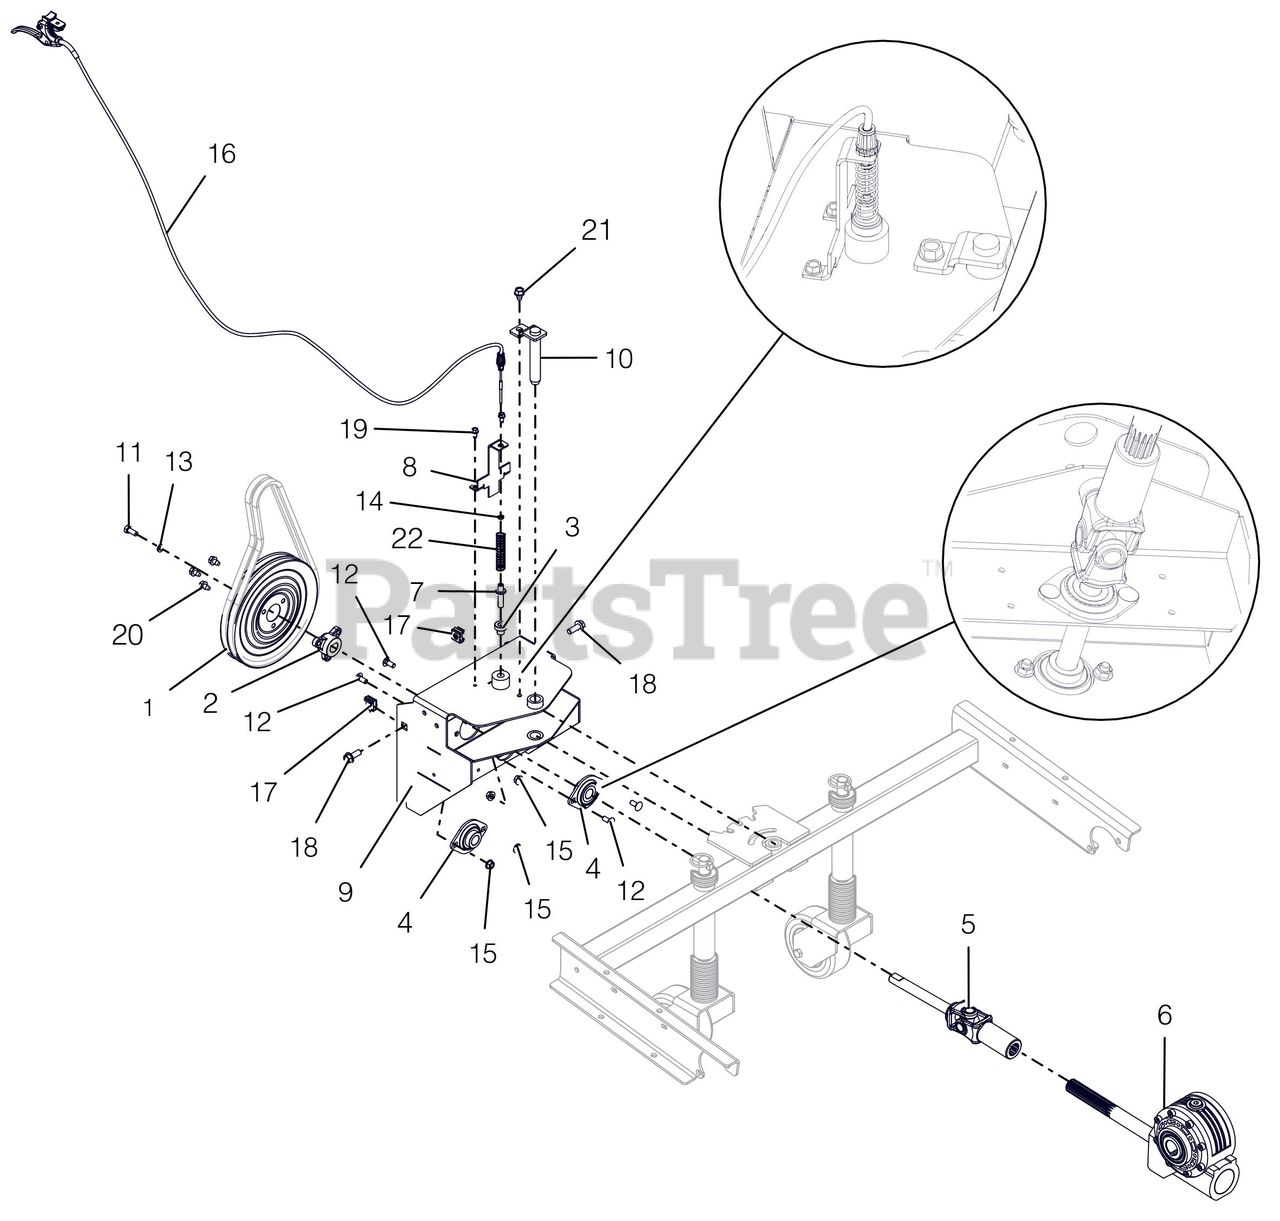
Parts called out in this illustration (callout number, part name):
1	PULLEY, SPIN FORM DUAL GROOVE
2	PULLEY HUB, BOLT-ON D-BORE .75
3	SPACER -FLANGED .390X.500X.781
4	BEARING, 2 BOLT FLANGE -.75 ID
5	DRIVELINE, SERIES 07 (U-JOINT)
6	GEARBOX, WORM - 8.25:1
7	PIN, ADJUSTABLE ANGLE BRUSH
8	BRKT, PIN HOLDER
9	ADAPTER, BRUSH
10	WLDMT, BRUSH PIN
11	BLT-HEX .31-24X.75 YWZC GR5
12	@BLT-RDHDSQNK .31-18X.75 G5YZ
13	WSHR-LK .312X.097 HVY YWZC
14	@NUT-HEX 10-24 YWZC
15	@NUT-LK-TOP-FLG .31-18 YWZC
16	CABLE, REMOTE BRUSH LOCK
17	NUT-RETNR .38-16 TINRMAN
18	BLT-SERHFWH .375-16X1.0 YWZC
19	SCR-TAP .25-20X.50 HWH TR YWZ
20	@SCR-TAP .31-18X.50 HWH TR YWZ
21	@SCR-TAP .38-16X.50 HWH TR YWZ
22	SPRING, COMPRESSION
